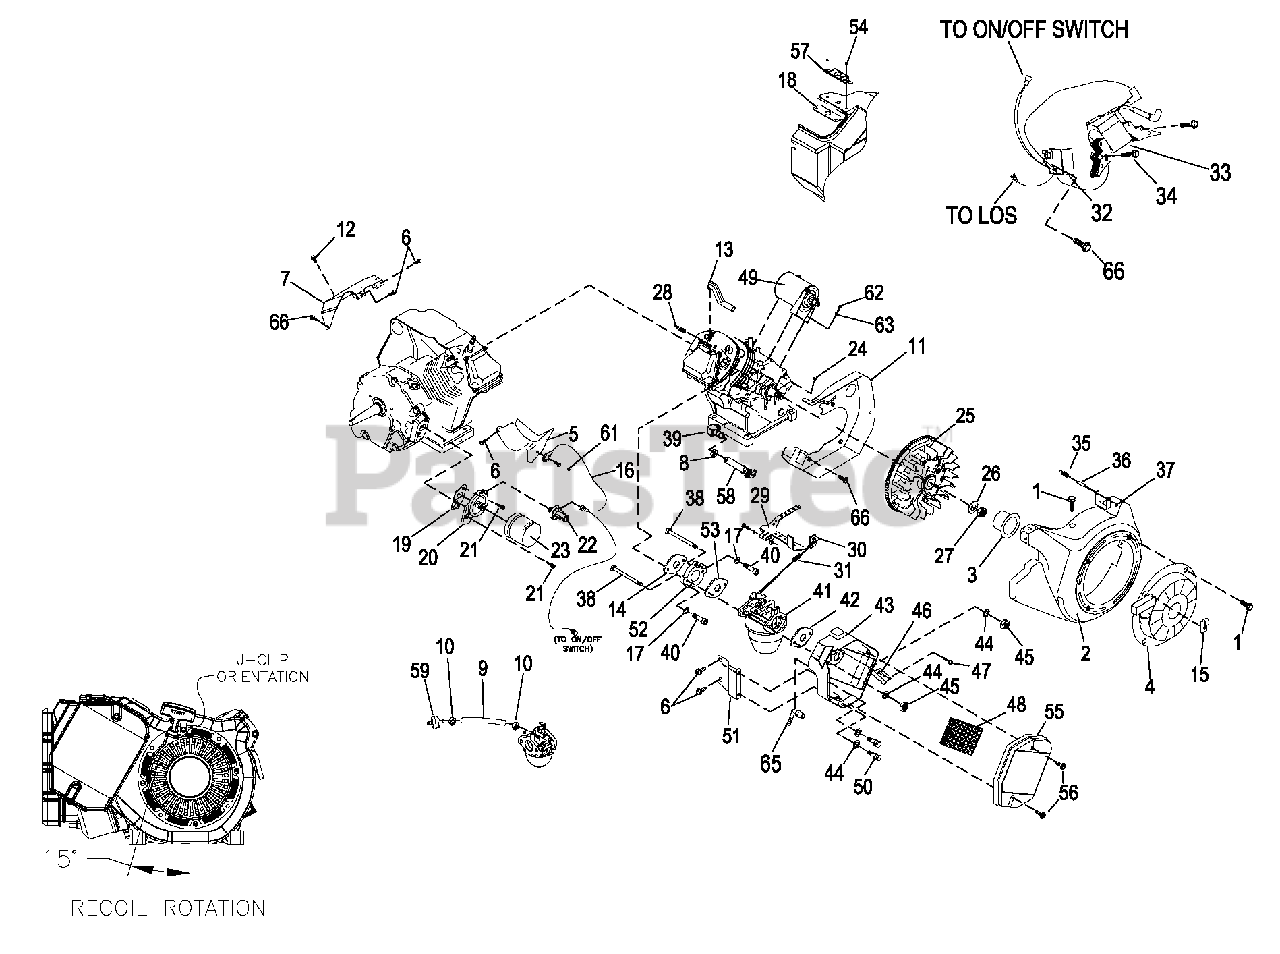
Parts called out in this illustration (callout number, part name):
1	SCREW HHTT M6-1.0 X 8 ZYC
2	ASSEMBLY, BLOWER HOUSING
3	PULLEY STARTER LARGE FRAME
4	RECOIL STARTER LARGE FRAME
5	WRAPPER, BOTTOM 12 HP HS
6	SCREW HHTT M6-1.0 X 10 YELLOW CHROME
7	WRAPPER, TOP REGULAR STEEL
8	CLAMP,HOSE OETIKER STPLSS 18.5
9	FUEL HOSE, 250 MM LONG
10	CLAMP HOSE BAND .41
11	BACKPLATE
12	SCREW, HHTT 5/16-18X1/2" CLEAR
13	HOSE, BREATHER GH410 ENGINES
14	GASKET, INTAKE ADAPTER
15	CLIP-J, VINYL COAT
16	WIRE HARNESS, 410 ENGINE SWITCH WIRING
17	WASHER, LOCK M6-1/4
18	BACK PLATE
19	GASKET,OIL FILTER ADAPTER
20	ADAPTER, OIL FILTER
21	SCREW, SHC M8-1.25 X 30 G12.9
22	SWITCH, HOBBS OIL PRESSURE 5PSI
23	FILTER, OIL BLACK 75 LONG
24	KEY, WOODRFF 4 X 19D
25	FLYWHEEL, RING GEAR 27 DEG
26	WASHER,BELV-20 X 2.2
27	NUT HEX M20-1.5 G8 YLW CHROME- FLYWHEEL
28	SPARKPLUG, CHAMPION RC14YC 0.030"
29	ASSEMBLY,GOVERNOR LEVER 12HP
30	ROD, GOVERNOR CONTROL
31	SPRING, ANTI-LASH
32	OIL PRESSURE SHUTDOWN MODULE
33	ASSEMBLY, IGNITION ADV NO DIODE GH410
34	SCREW HHFC M6-1.0 X 25 G8.8
35	SPRING GOVERNOR 320/360/410
36	BOLT, GOVERNOR ADJUSTMENT M5
37	NUT, HEX LOCK M5-0.8 NYLON INSERT ZINC
38	BOLT, CARBURETOR MOUNTING
39	BARBED ELBOW 90 DEG 3/8" NPT X 3/8"
40	SCREW, SHC M6-1.0 X 20 G12.9 ZINC PLATED
41	CARBURETOR ASSEMBLY, 410HS
42	GASKET, AIR CLEANER
43	BASE, AIR CLEANER 410 HI FLOW XP PORT
44	WASHER, FLAT M6
45	NUT, HEX LOCK M6-1.0 NYLON INSERT
46	PLATE, SPITBACK
47	SCREW HWHTF 8-18 X 0.5 HI-LOW
48	ELEMENT, AIR FILTER
49	STARTER, ASSEMBLY
50	SCREW, HHC M6-1.0 X 16 W/ LOCK WASHER
51	BRACKET, AIR CLEANER
52	ADAPTER, "K"
53	GASKET, CARBURETOR/MANIFOLD
54	RIVET, 1/8"
55	COVER, AIR CLEANER 13GN
56	BOLT, AIR CLEANER COVER
57	BRACKET, CHOKE CABLE
58	ASSY OIL DRAIN HOSE, 6" LONG ORANGE
59	FUEL FILTER
61	GROMMET
62	SCREW SHC M8-1.25 X 40 C8.8
63	WASHER, LOCK M8-5/16
65	BARBED ELBOW, 90 DEGREE 1/8NPT (0H6225 ONLY)
66	SCREW HHFC M6-1.0 X 12
